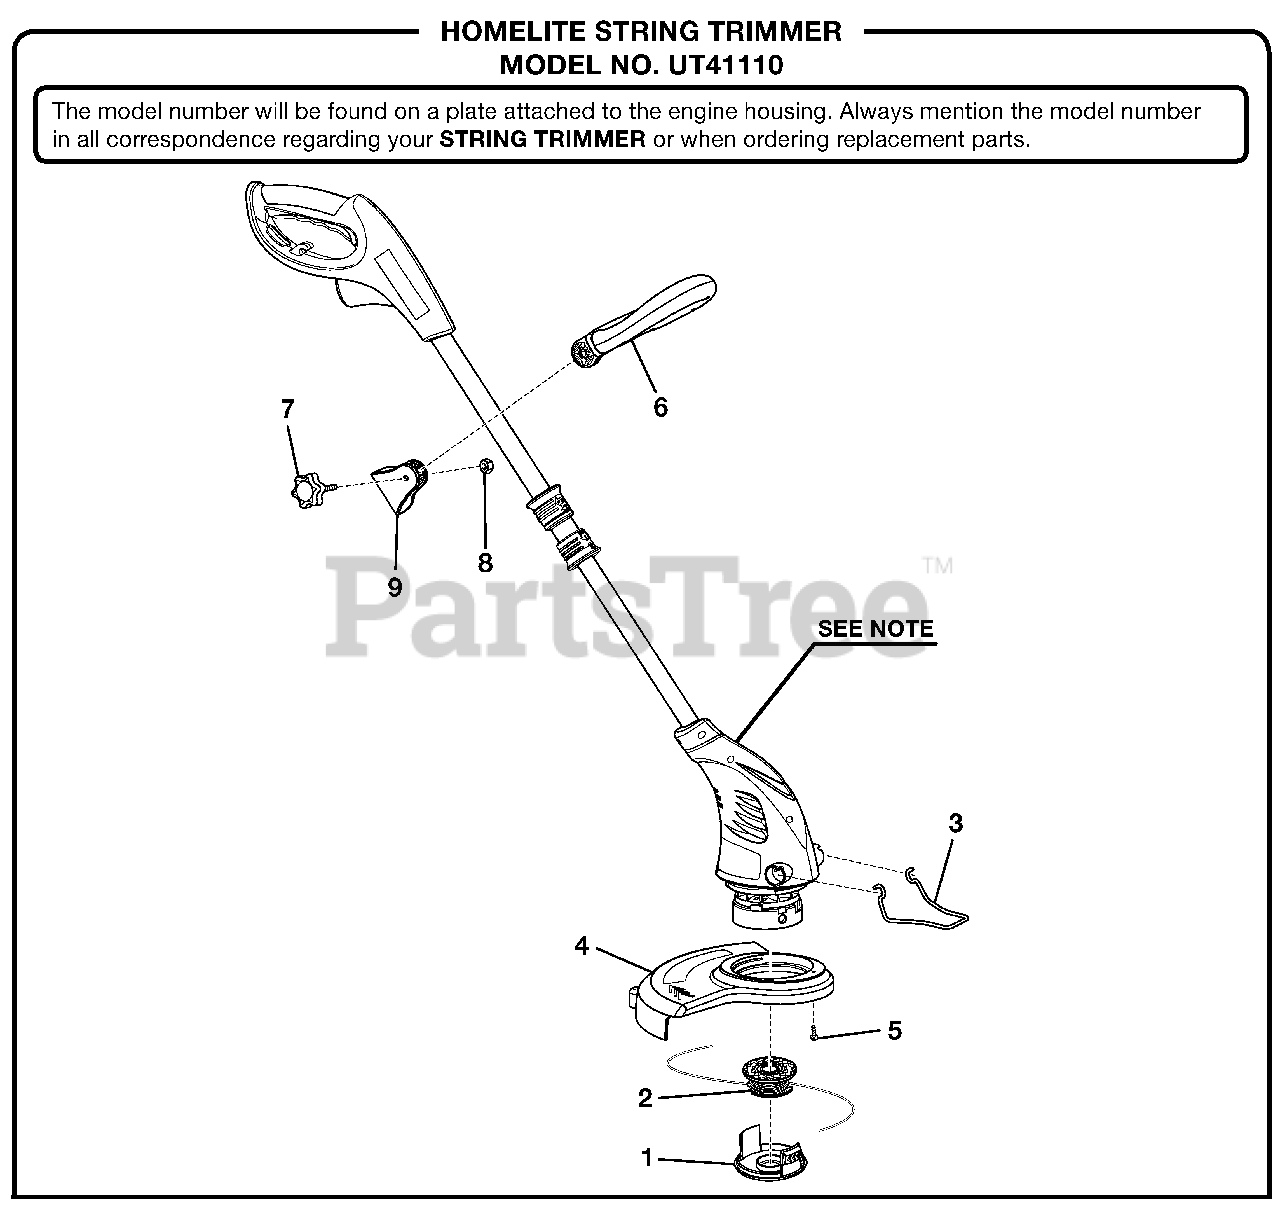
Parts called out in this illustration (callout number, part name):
3	Edger Guide
4	Grass Shield
5	Screw
6	Front Handle
7	Knob Screw
8	Hex Nut
